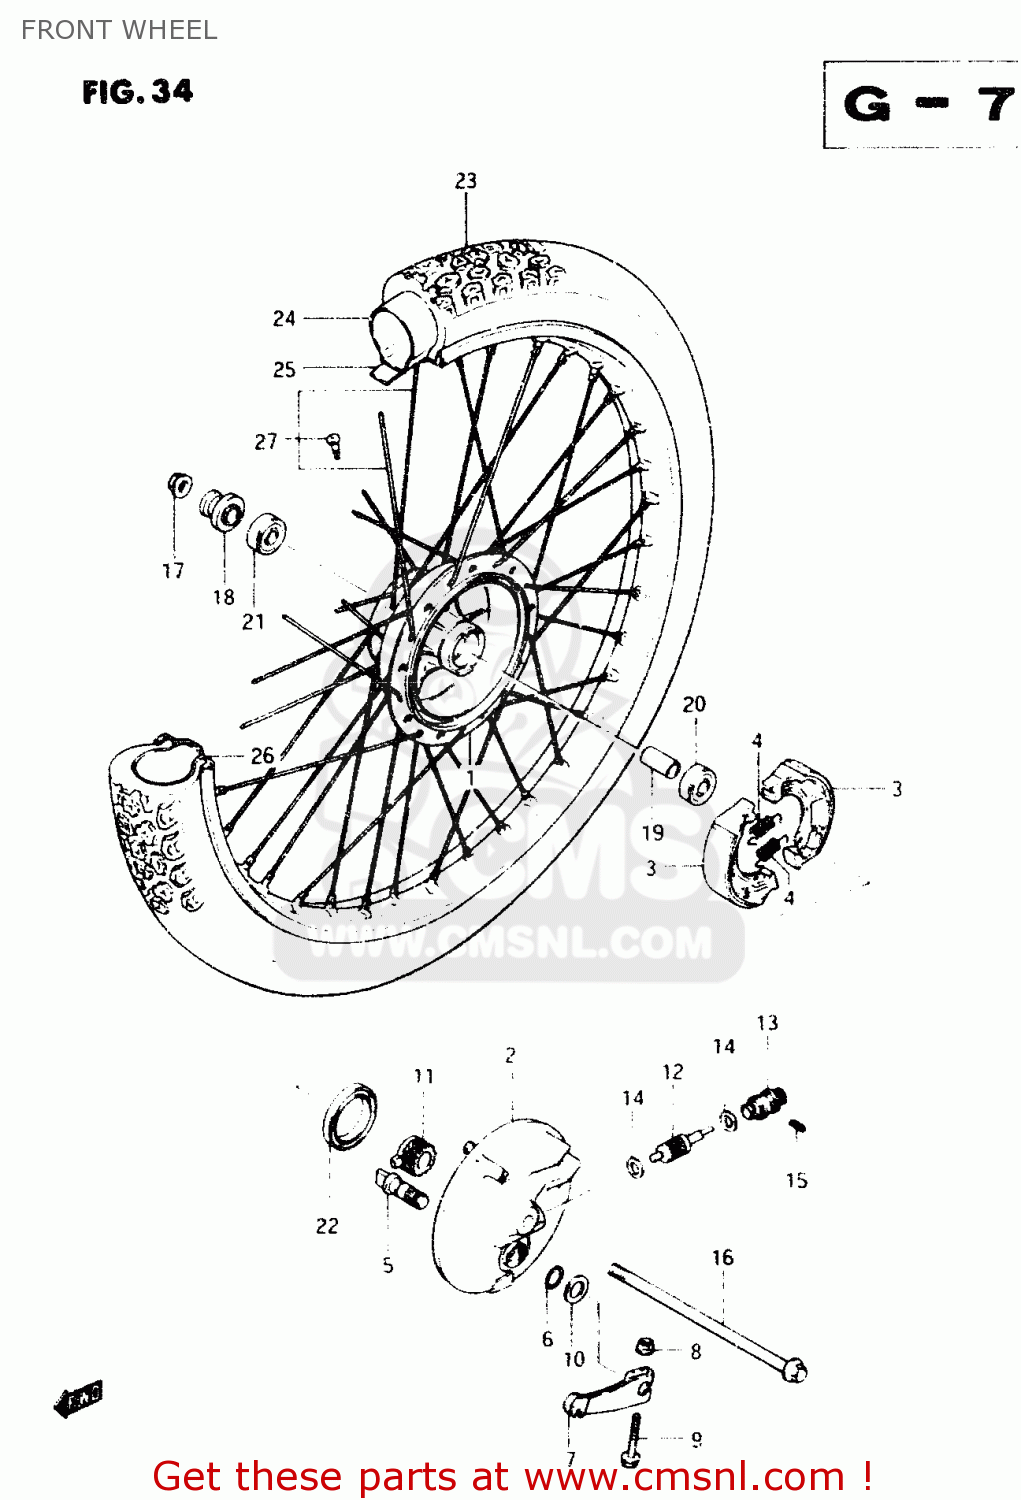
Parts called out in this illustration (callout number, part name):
1	HUB,FR WHEEL
2	PANEL,FR BRAKE ANCHOR
3	SHOE SET,BRAKE (MCA)
4	SPRING(L:34)
5	CAM,FRONT BRAKE
6	O-RING (D:2.4 ID:13.8)
7	LEVER,FR BRAKE CAM
8	NUT
9	BOLT
10	WASHER (14.2X22X1)
11	GEAR,SPEEDOMETER(NT:26)
12	PINION,SPEEDOMETER(NT:9)
13	BUSH,METER GEAR OUTER
14	WASHER (5.1X9X0.4)
15	SCREW
16	AXLE,FR
17	NUT
18	SPACER,FRONT AXLE,RIGHT
19	SPACER(10.2X16X47)
20	BEARING
21	BEARING
22	OIL SEAL (43X58X7)
23	TIRE, FRONT (2.50-21) IRC
24	TUBE ASSY,FR WHEEL INNER
25	PROTECTOR,WHEEL,INNER
26	RIM,FR WHEEL(1.40X21)
27	SPOKE ASSY,FR WHEEL
